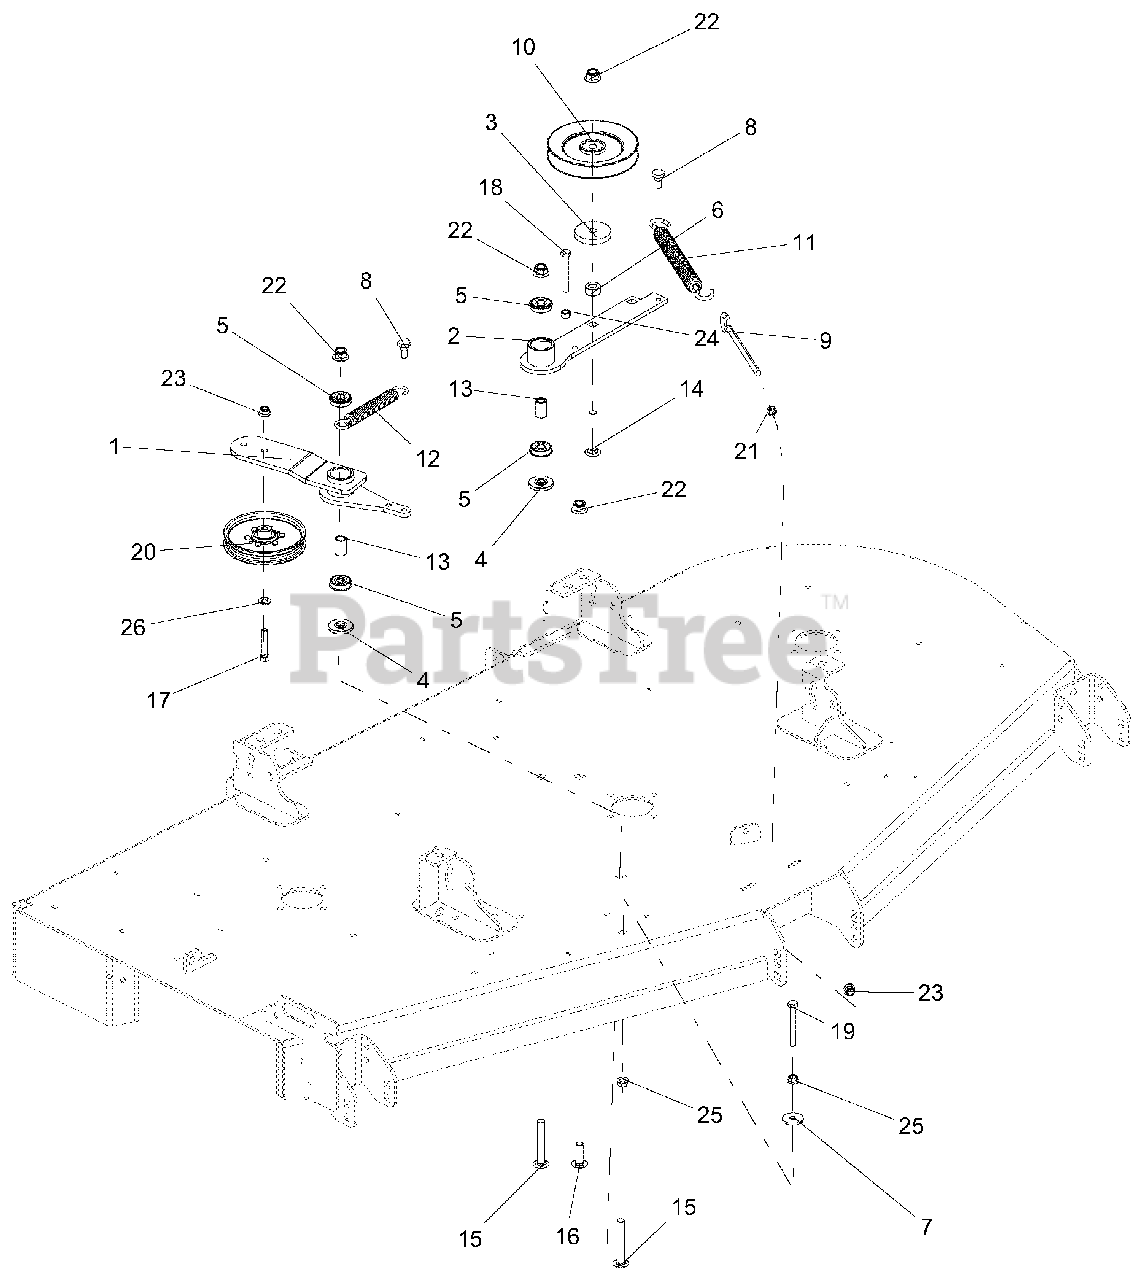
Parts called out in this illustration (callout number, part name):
1	WLDMT, DECK RH IDLER ARM
2	WLDMT, DECK PTO IDLER ARM-BLACK
3	CAP, IDLER BEARING SEALING
4	SPACER, IDLER ARM
5	BRG, BALL .501 X 1.38 X .438 SEALED
6	BSHG, SPCR .502 X .997.50 PM
7	WSHR-FL-STL .406X1.375X.135 YZ
8	BLT, SHLDR EP .38-16X.30 HEX YZ
9	BOLT, .38-16X6.00 .62 DIA EYE
10	SHEAVE, .50" ID X 6.00" OD V-IDLER
11	SPRG, EXTENSION
12	SPRG, EXTENSION
13	SPACER, .510 X .750 X 1.148
14	BLT-RDHDSQNK .50-13X3.00YG5
15	BLT-RDHDSQSHNK .50-13X3.25 YWZC
16	BLT-RDHDSQSHNK .50-13X1.50 YWZC
17	BLT-HEX .38-16X2.00 GR5 YWZC
18	BLT-HEX .38-16X2.75 GR5 YWZC
19	BLT-HEX .38-16X3.00 GR5 YWZC
20	PULLEY, FLAT IDLER .500 X .375 W/BRG
21	NUT, JAM .375-16 YWZC
22	NUT-LK-NYL-FLG .50-13 YWZC
23	NUT-LK-NYL-FLG .38-16 YWZC
24	NUT-HEX .38-16 YWZC
25	@NUT-SPNLK-FLG .375-16 YWZC
26	WSHR-FL-STL.406X.812X.065ZYW
